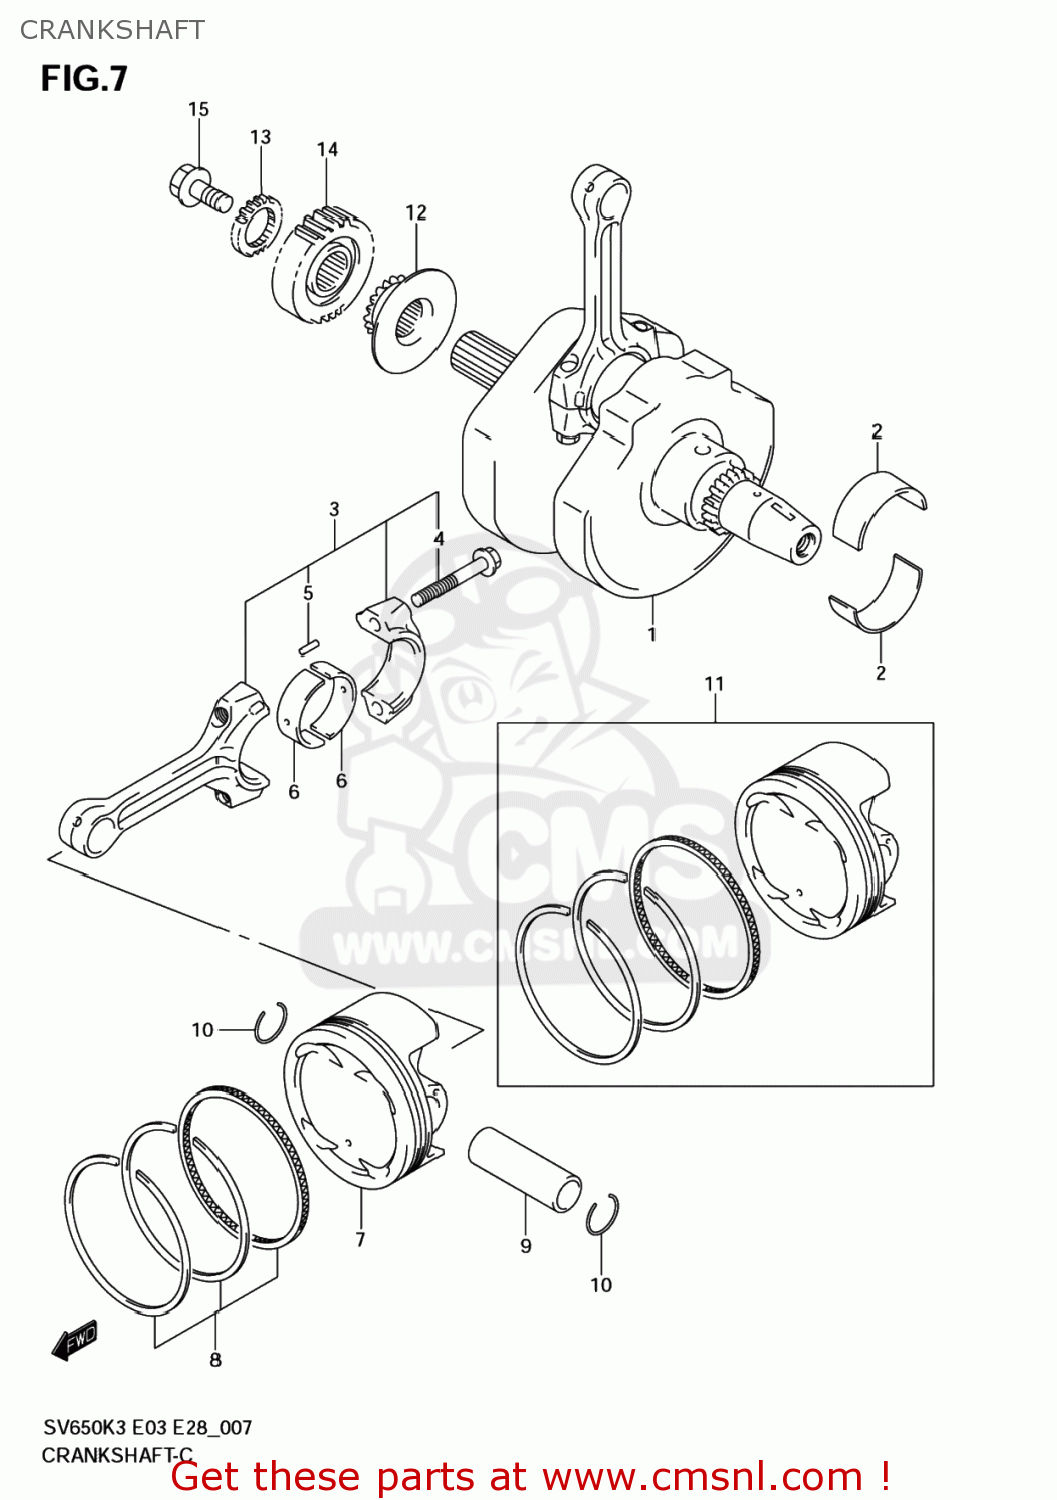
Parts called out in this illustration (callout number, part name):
1	CRANKSHAFT
2	BEARING,CRANKSHAFT
3	CONNROD ASSY
4	BOLT,CONNECTING ROD
5	PIN,CONNECTING ROD
6	BEARING,CRANK PIN
7	PISTON
8	RING SET,PISTON
9	PIN,PISTON
10	CIRCLIP,PISTON PIN
11	PISTON SET(OS:0.5)
12	SPROCKET,CAM CHAIN DRIVE
13	GEAR,WATER PUMP DRIVE
14	GEAR,PRIMARY DRIVE
15	BOLT(10X19)
